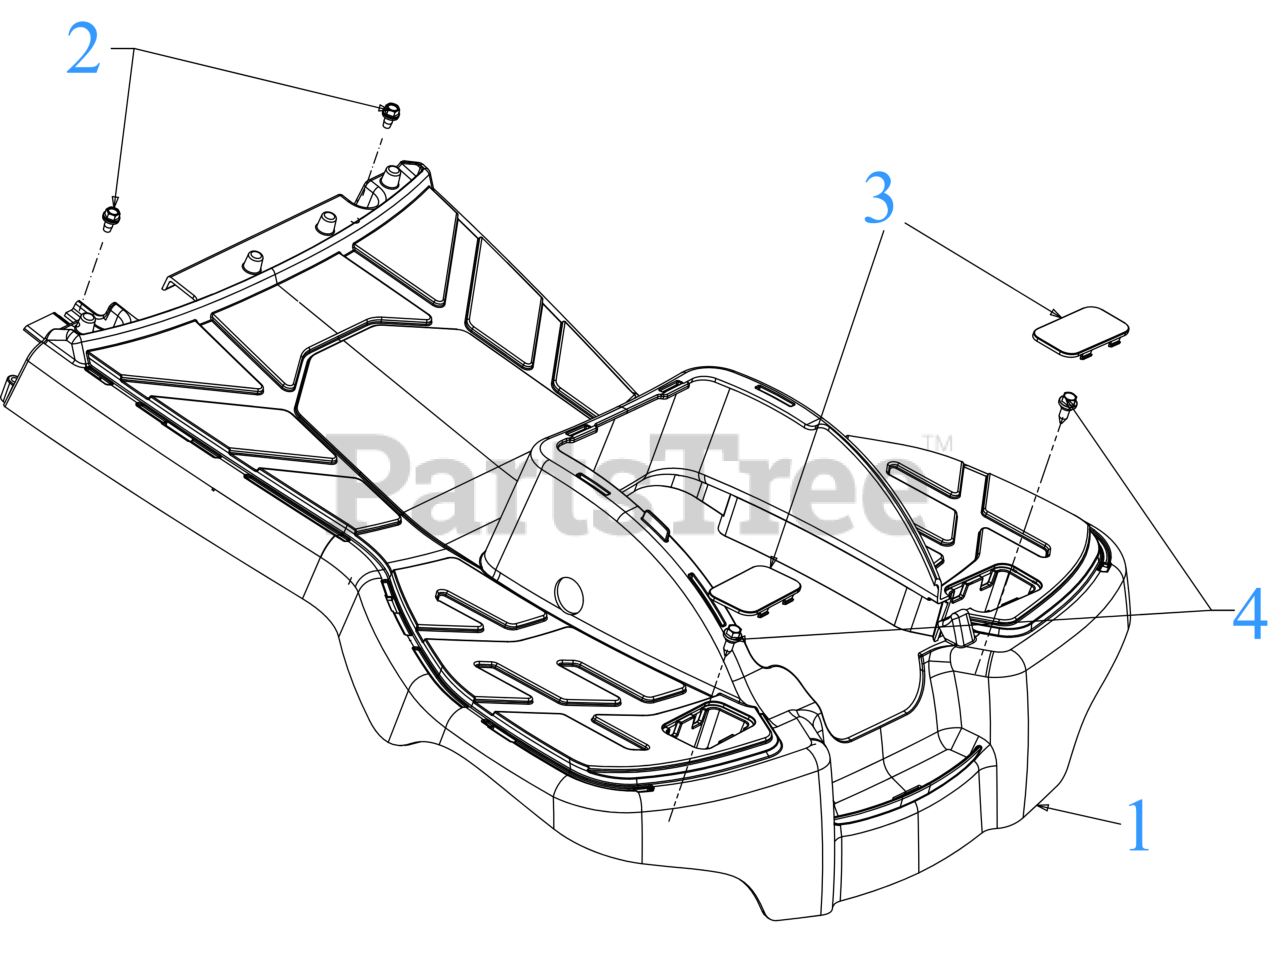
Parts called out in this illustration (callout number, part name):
1	RUNNING BOARD
2	SCREW 1/4-20 x .50
3	RUNNING BOARD PLUG
4	SHOULDER SCREW
